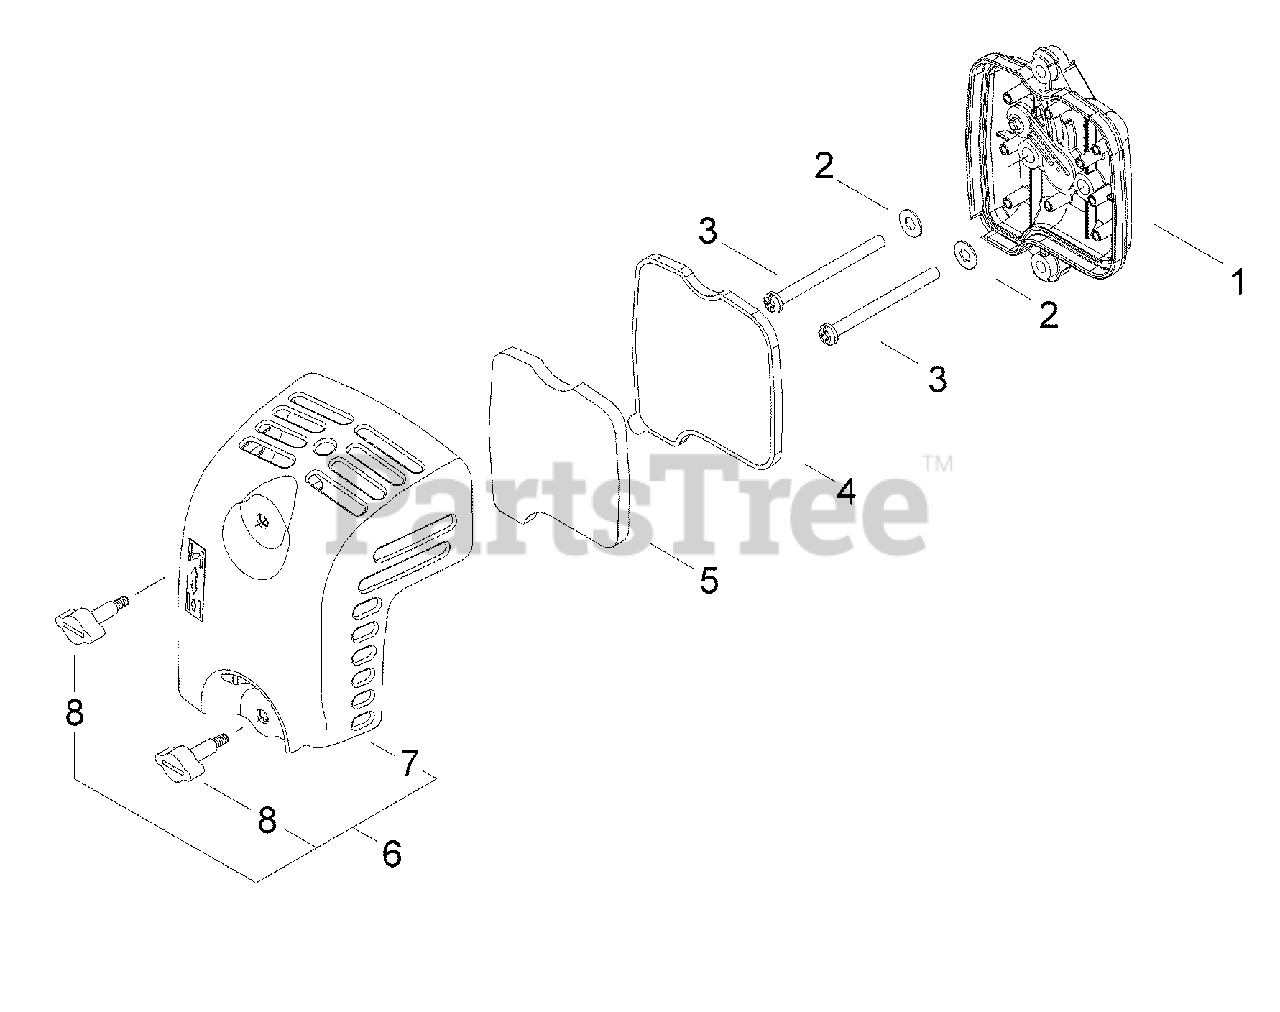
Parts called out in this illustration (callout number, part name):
1	AIR FILTER CASE ASSY
2	WASHER - 5
3	SCREW - 5X60
4	FILTER, AIR
5	PRE-FILTER - FOAM
6	AIR FILTER COVER ASSY
7	COVER, AIR FILTER
8	THUMBSCREW
